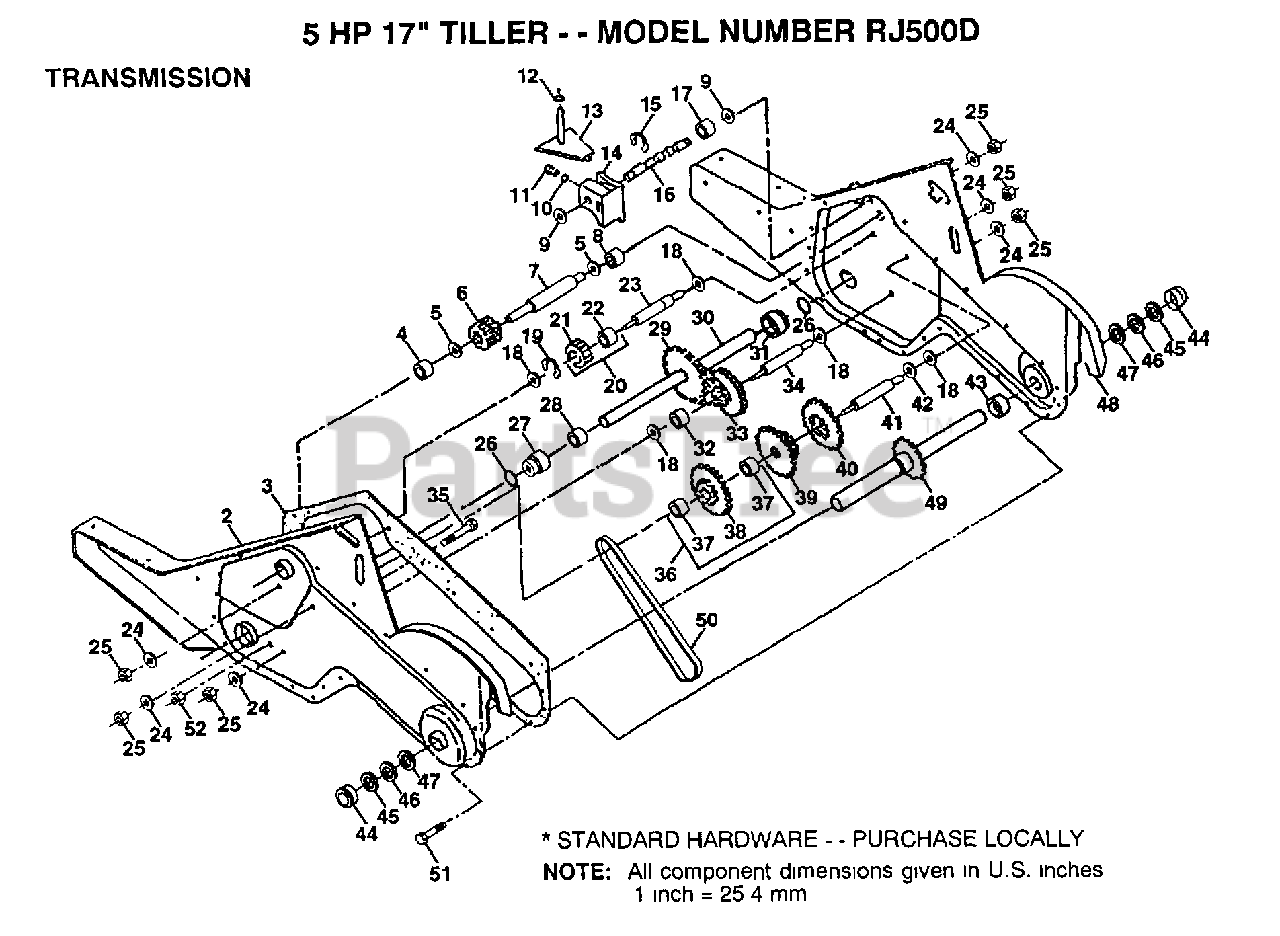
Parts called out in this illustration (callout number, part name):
3	GASKET TI
4	NEEDLE BRNG LT
5	"T, BEARING"
6	PINION-INPUT CRT
7	SHAFT-INPUT CRT
8	"TI, BEARING"
9	WASHER SEAL CRT
11	SPRING-SHIFT CRT
12	O-RING TI
13	ARM ASSY CRT
14	SHIFT FORK TI
15	KLIP RING
16	SHAFT SHIFT CRT
17	SPACER SPLIT CRT
18	WASHER
19	KLIP RING
20	GEAR ASSY CRT
21	GEAR-REV IDLR CRT
22	NEEDLE BEARING TI
23	SHAFT CRT
24	LOCKWASHER
25	NUT.ASF.HEX.7/16
26	O RING CRT
27	"CRT, BEARING"
28	BUSHING TI
29	CHAIN CRT
32	SPACER TI
33	SPRCKT 8 GEAR CRT
34	SHFT 2ND RED. CRT
35	SCRW WHIZ LOK CRT
36	SPROCKET ASM.
37	BEARING
39	GEAR TI
40	GEAR TI
41	REDUCTION SHFT TI
42	BRNG RACE
43	SPACER TI
44	CUP.FORMED.
45	RING SPIRAL CRT
49	TINE SHAFT
50	CHAIN.50 LINK TI
51	SCREW CRT
52	NUT.HEX.5/16-18
